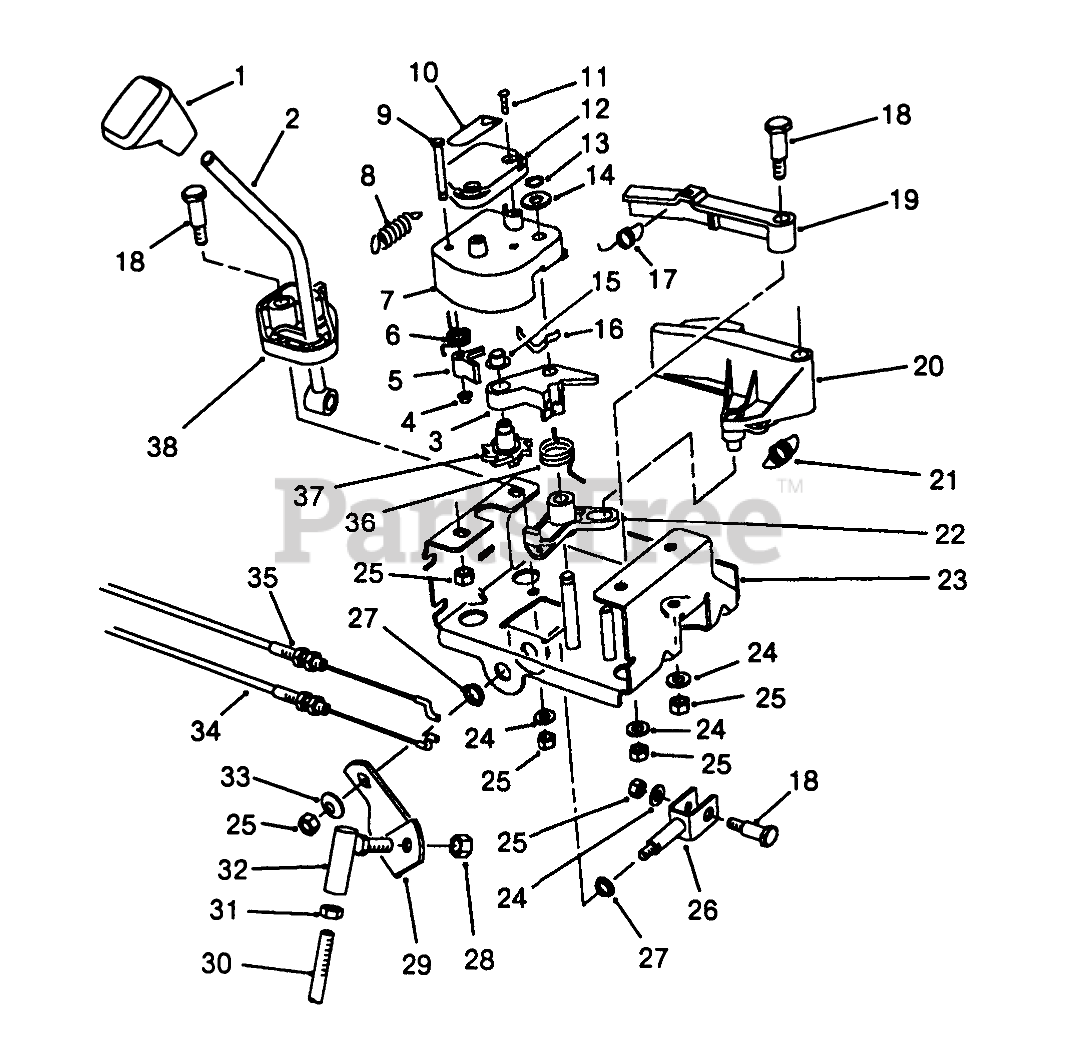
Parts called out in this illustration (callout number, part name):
1	KNOB-SHIFT
2	SHIFT ROD WA
3	LEVER-WHEEL, INDEX
4	NUT-PUSH
5	TANG-INDEX
6	SPRING-TORSION
7	LATCH-LEVER
8	SPRING-EXTENSION
9	PIN-TANG
10	DECAL
11	SCREW-PPH
12	COVER-LATCH
13	RING-RETAINING
14	WASHER-THRUST
15	RETAINER-PUSH ON
16	SPRING-FLAT
17	SPRING-EXTENSION
18	SCREW-SHOULDER
19	LEVER-LOCKOUT
20	LEVER-REVERSE
21	SPRING-EXTENSION
22	LEVER-REVERSE, SWITCH
23	Frame-Control
24	WASHER-PLAIN
25	NUT-LOCK, NI
26	CLEVIS WA
27	BUSHING
28	NUT-LOCK
29	BRACKET-SHIFT
30	LOWER SHIFT ROD
31	NUT-HJ
32	JOINT-BALL
33	WASHER-BELLEVILLE
34	CABLE-GEARBOX
35	CABLE-ARM, LATCH
36	SPRING-TORSION
37	WHEEL-INDEX
38	BASE-LOCKOUT
